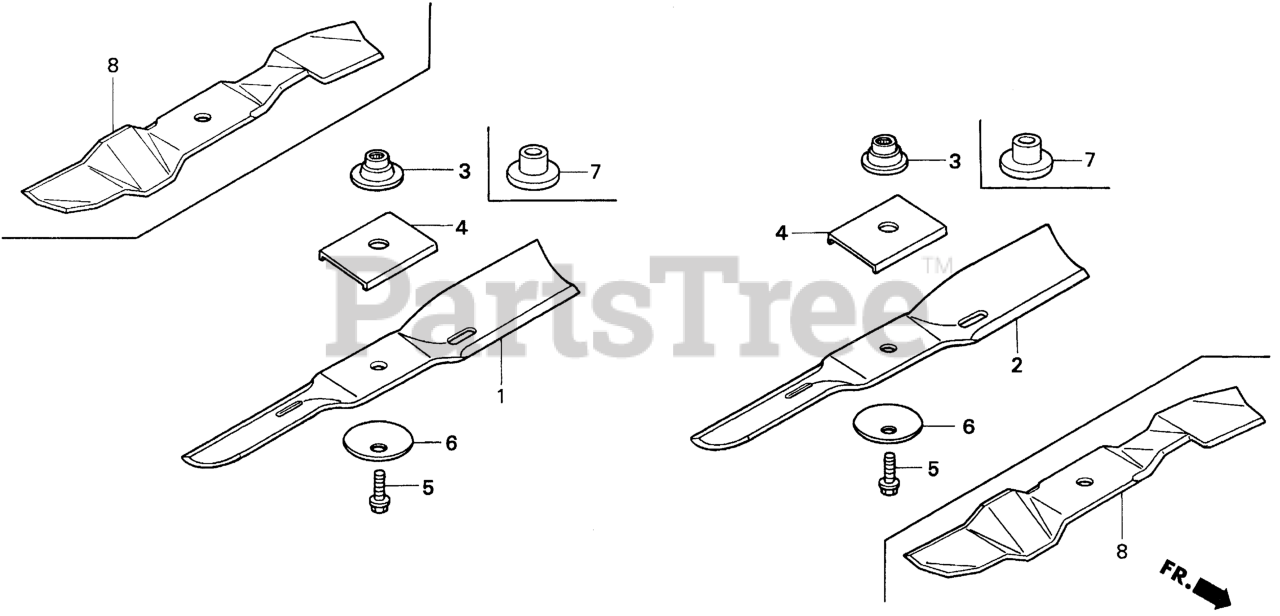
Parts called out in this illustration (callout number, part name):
4	HOLDER, BLADE (B)
5	BOLT, BLADE HOLDER (10X28)
6	WASHER, BLADE
7	HOLDER, BLADE
8	BLADE, ROTARY
